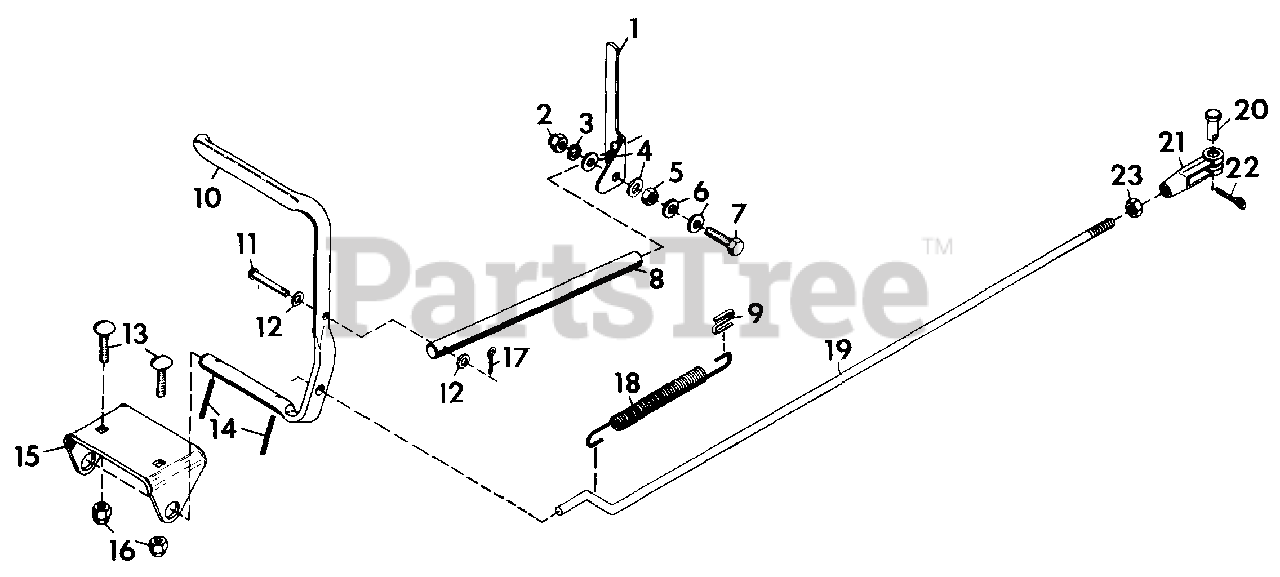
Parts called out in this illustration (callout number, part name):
1	ARM, PARKING BRAKE LOCK
2	NUT, LOCK 3/8-16
3	WASHER, LOCK 3/8
4	WASHER, NYLON .375X.75X.06
5	NUT, JAM 3/8-16 HEX
6	WASHER, FLAT .406X.812X.065
7	BOLT, HEX 3/8-16X1.25
8	ROD
9	CLIP, SPRING
10	PEDAL, BRAKE
11	PIN, CLEVIS .25X1.50
12	WASHER, FLAT .281X.625X.065
13	BOLT, CARRIAGE 3/8-16X.75
14	PIN, SPRING .187X1.25
15	BRACKET, BRAKE PEDAL
16	NUT, LOCK 3/8-16
17	PIN, COTTER .06X.75
18	SPRING, EXT. 5.50X.50X20 RATE
19	ROD, BRAKE
20	PIN, CLEVIS 5/16X.812
21	YOKE
22	PIN, COTTER .09X.75
23	NUT, HEX 5/16-24
